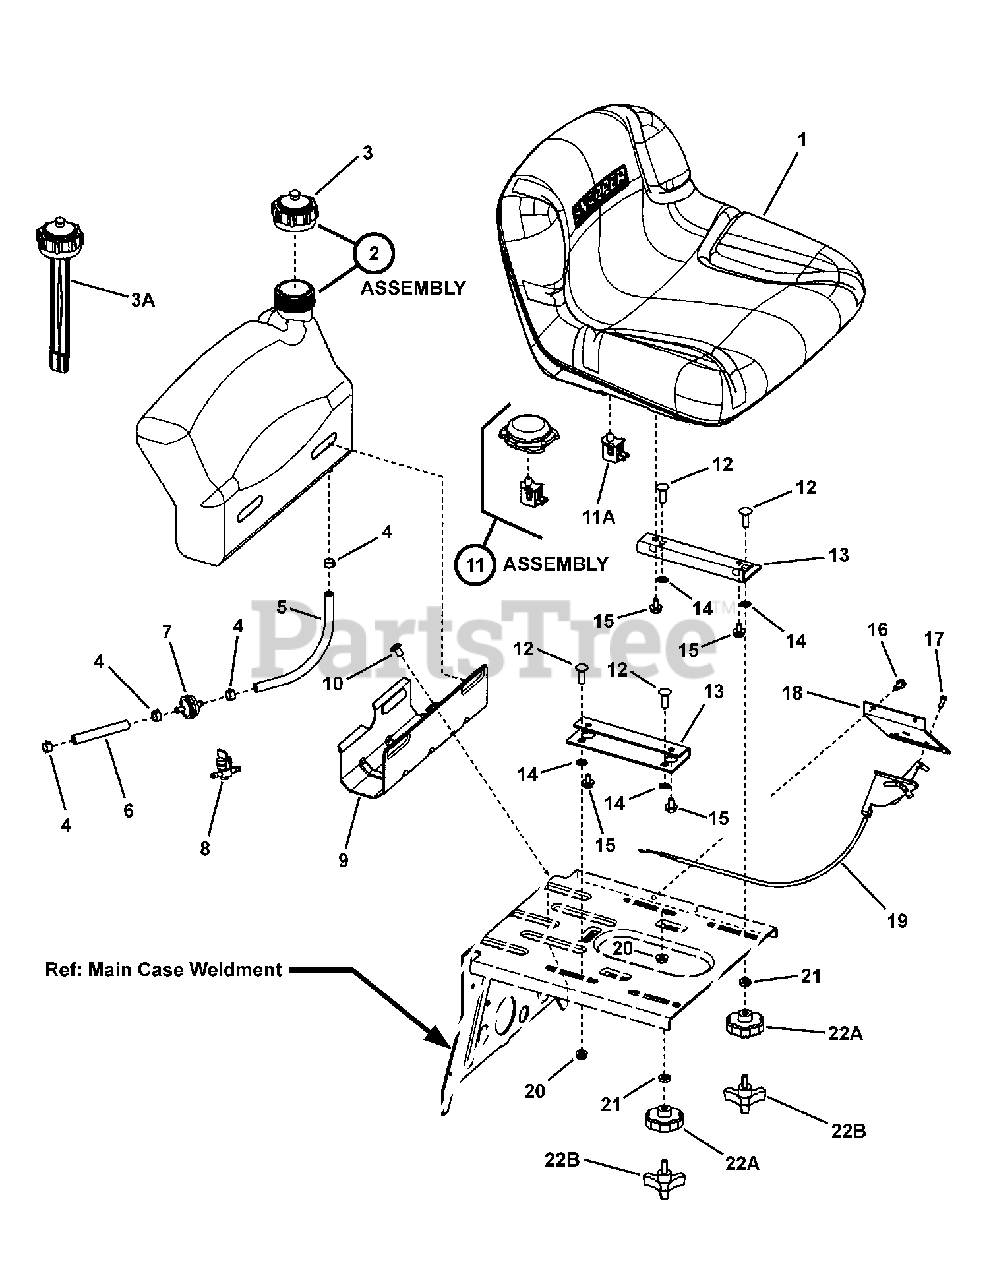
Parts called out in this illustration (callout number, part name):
1	SEAT, Operator (11.58" tall) (shown) (Michigan V-2400 Series)
1	SEAT, Operator (9.30" tall) (Michigan V-2300 Series)
2	ASSEMBLY, Fuel Tank (Includes item 3)
2	ASSEMBLY, Fuel Tank with Gauge (Includes item 3A)
3	CAP, Fuel Tank
3A	CAP, Fuel Tank w/Gauge
4	CLAMP, Fuel Line
5	HOSE, Fuel (1/4" I.D. x 8-1/2" long)
5	HOSE, Fuel (1/4" I.D. x 12-1/2" long)
5	HOSE, Fuel (1/4" I.D. x 6-1/2" long)
6	HOSE, Fuel (1/4" I.D. x 3-1/2" long)
7	FILTER, Fuel (In-Line)
8	VALVE, Fuel Shut-Off (Accessory)
9	BRACKET, Fuel Tank (Rear)
10	SCREW, 5/16-18 x 1/2" Pan Head Self-Tap (Torx #T-40)
11	SWITCH, Seat, Quick Mount (NC)
11A	SWITCH, Seat (NC)
12	BOLT, 5/16-18 x 1" Square Neck Carriage, GR 5 YZ
13	BRACKET, Seat
14	RETAINER, 5/16" Bolt
15	BOLT, 5/16-18 x 1/2" Hex Flange Nyloc
16	SCREW, 1/4-20 x 1/2" Hex Washer Self-Tap
17	SCREW, #10-24 x 1/2" Hex Washer Self-Tap (Torx)
18	PLATE, Throttle Control
19	CONTROL, Throttle (23.6" long) (Briggs Engines)
19	CONTROL, Throttle (34.6" long) (Kohler Engines)
19	CONTROL, Throttle (34.6" long) (Honda Engines)
20	NUT, 5/16-18 Hex Flange Top Lock
21	SPACER, .33 x .63 x .156
22A	KNOB, Fluted, 5/16-18 internal thread (2.15 O.D.)
22B	KNOB, 3-Prong, 5/16-18 x 3/4" external thread
